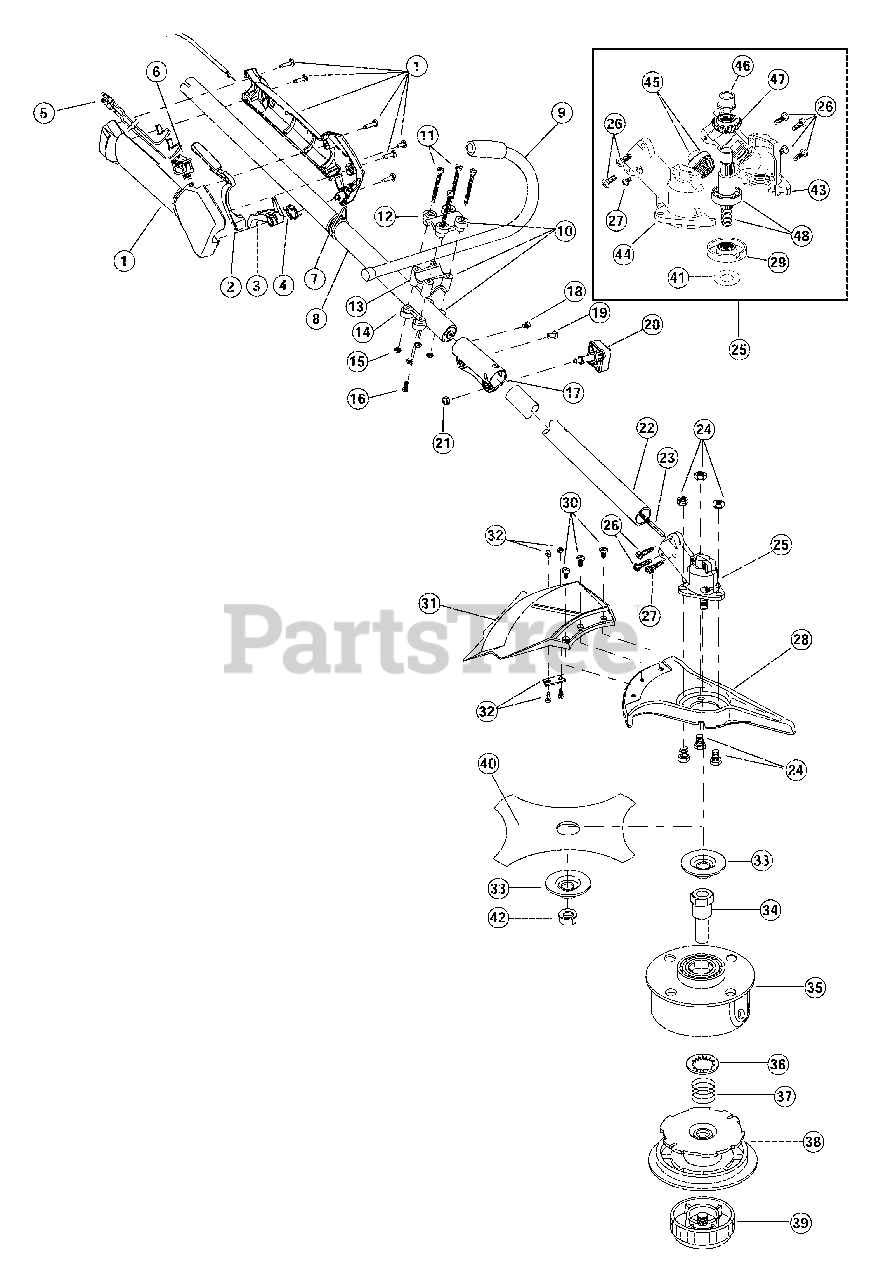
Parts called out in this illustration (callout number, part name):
1	Throttle Housing Assembly
2	Throttle Trigger Lock-Out
3	Throttle Trigger
4	Throttle Trigger Spring
5	Lead Wire Assembly
6	Switch Assembly
7	Harness Clip
8	Upper Drive Shaft Housing Assembly
9	J-Handle Assembly
10	Handle Bracket Assembly
12	Upper Handle Clamp
13	Middle Handle Clamp
14	Lower Handle Clamp
16	Anti-Rotation Screw
17	Split Boom Coupler
20	Adjustment Knob
21	Knob Retaining Nut
22	Lower Drive Shaft Housing Assembly
23	Lower Flexible Drive Shaft
24	Shield Mount Screw Assembly
25	2 piece Gearbox Assembly
26	Gearbox Mounting Hardware
27	Anti-Rotation Screw
28	Blade Shield/Shield Mount
29	Blade Driver
30	Shield Mounting Screw
31	Shield Assembly
32	Blade Assembly
33	Retaining Washer
34	Spool Shaft
35	Outer Spool Assembly
36	Retainer
38	Inner Reel
39	Bump Head Knob Assembly
40	4-Tooth Blade
41	Palnut
42	Nut
43	Left Housing
44	Right Housing
45	Pinion Gear Assembly
46	Output Shaft Bushing
47	Output Shaft Gear
48	Output Shaft Assembly
